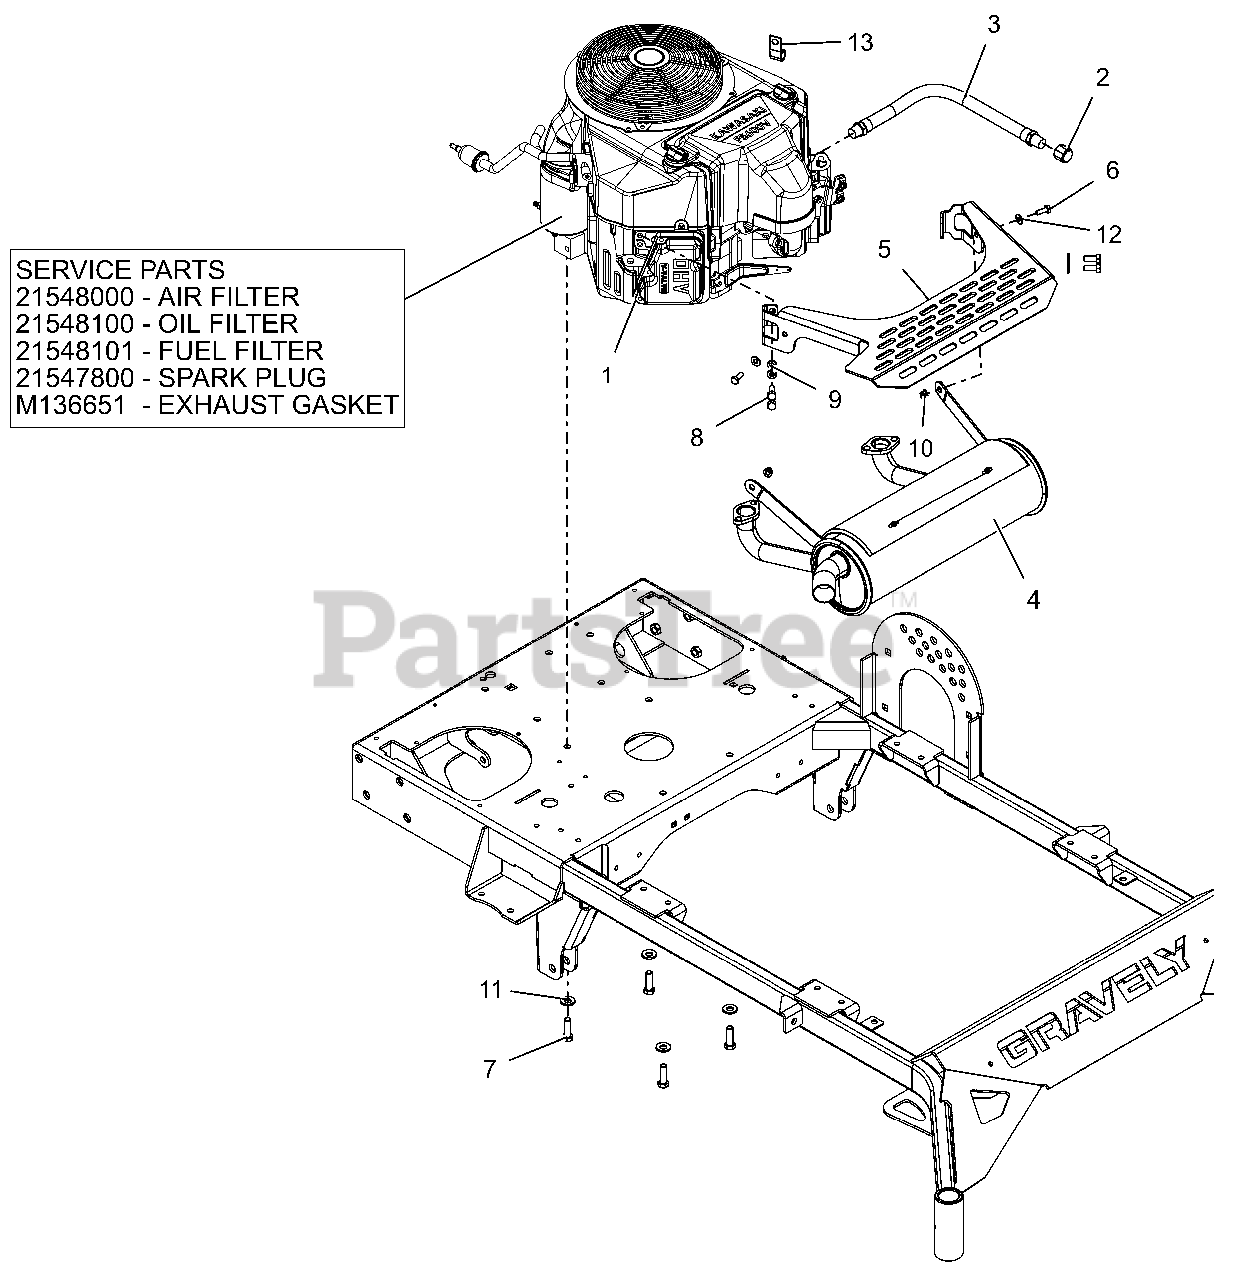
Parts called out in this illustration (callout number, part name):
1	ENGINE, KAWASAKI FS691
1	AIR FILTER, KAWASAKI FR
1	OIL FILTER, KAWASAKI FR
1	FUEL FILTER-KAWASAKI FR
1	SPARK PLUG, KAWASAKI FR
1	GASKET, MUFFLER #
2	PIPE CAP 3/8 NPT FEMALE
3	DRAIN, M20 OIL
4	EXHAUST, KAWASAKI PROSTANCE
5	KIT, MUFFLER SHIELD W DECALS
6	@BLT-HEX .25-20X.75 GR5 YWZC
7	BLT-HEX.38-16X1.25 G5YZ NYTORQ
8	@BLT-HEX M8-1.25X20 YWZC
9	@WSHR-LK .31X.078 REG YWZC
10	@NUT-LK-NYL-FLG .25-20 YWZC
11	WASHER, 3/8" SPRING DISC
12	@WSHR-FL-STL.281X.62X.065 YWZC
